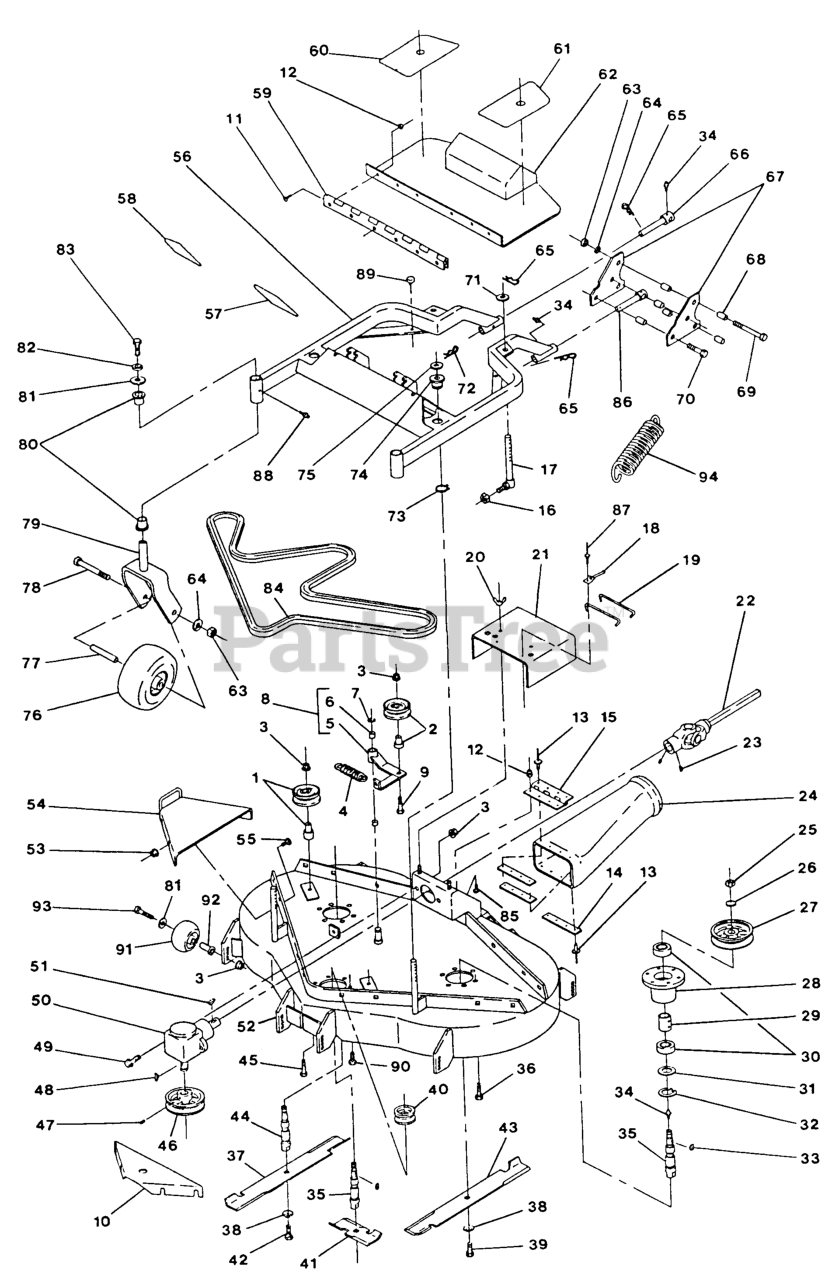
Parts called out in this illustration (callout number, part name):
1	KIT,IDLER & BUSHING
4	SPRING-IDLER, DECK
6	SLEEVE-BEARING
18	CLIP-DECK, HOLD UP ROD
20	WINGNUT-NYLOCK
26	WASHER-SPRING
29	SPACER,BEARING
31	SEAL,MECHANICAL DUST
32	RING,SNAP WLDS N5000-244
36	SCRW,TPTTE HH
38	WASHER-SPRING
42	SCREW-CAP,HH
47	SCREW-SET
50	GEARBOX, PEERLESS
54	WLD,GUARD BELT
57	PAD,ANTI SKID UPPER LH
58	PAD,ANTI SKID UPPER RH
59	HINGE,FLOORPAN
60	PAD,ANTI SKID LOWER RH
65	PIN,HAIR COTTER
74	BUSHING-DECK
75	WASHER-FLAT
84	BELT,DECK DRIVE
85	BOLT-CARR
87	Pop Rivet, Steel 3/16 X .250
91	ROLLER-SCALP, ANTI
92	BUSHING-ROLLER
93	SCRWCAPHH
